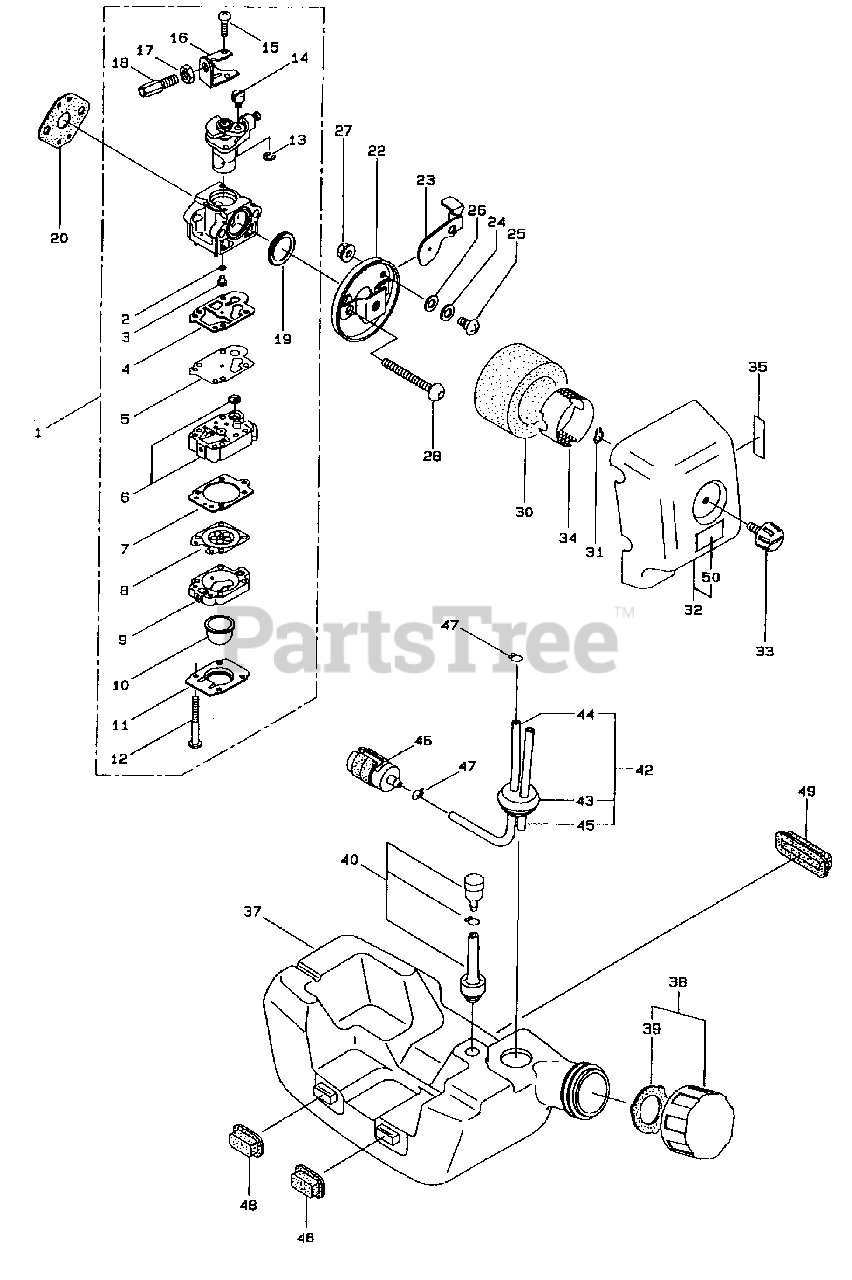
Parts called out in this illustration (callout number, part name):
1	Carburetor Assembly (Incl. Ref. # 2-19)
3	Main Jet
5	Diaphragm
6	Pump Body
8	Diaphragm
9	Purge Body
10	Primer Bulb
11	Cover Plate
15	Screw
23	Choke Valve
28	Cap Screw
30	Foam Element
31	Snap Ring
32	Air Filter Cover
37	Fuel Tank
38	Fuel Tank Cap Assembly (Incl. Ref. # 39)
40	Breather Assembly
42	Fuel Pipe Assembly (Incl. Ref. # 42-45)
44	Fuel Pipe
45	Return Pipe
46	Fuel Filter Assembly
